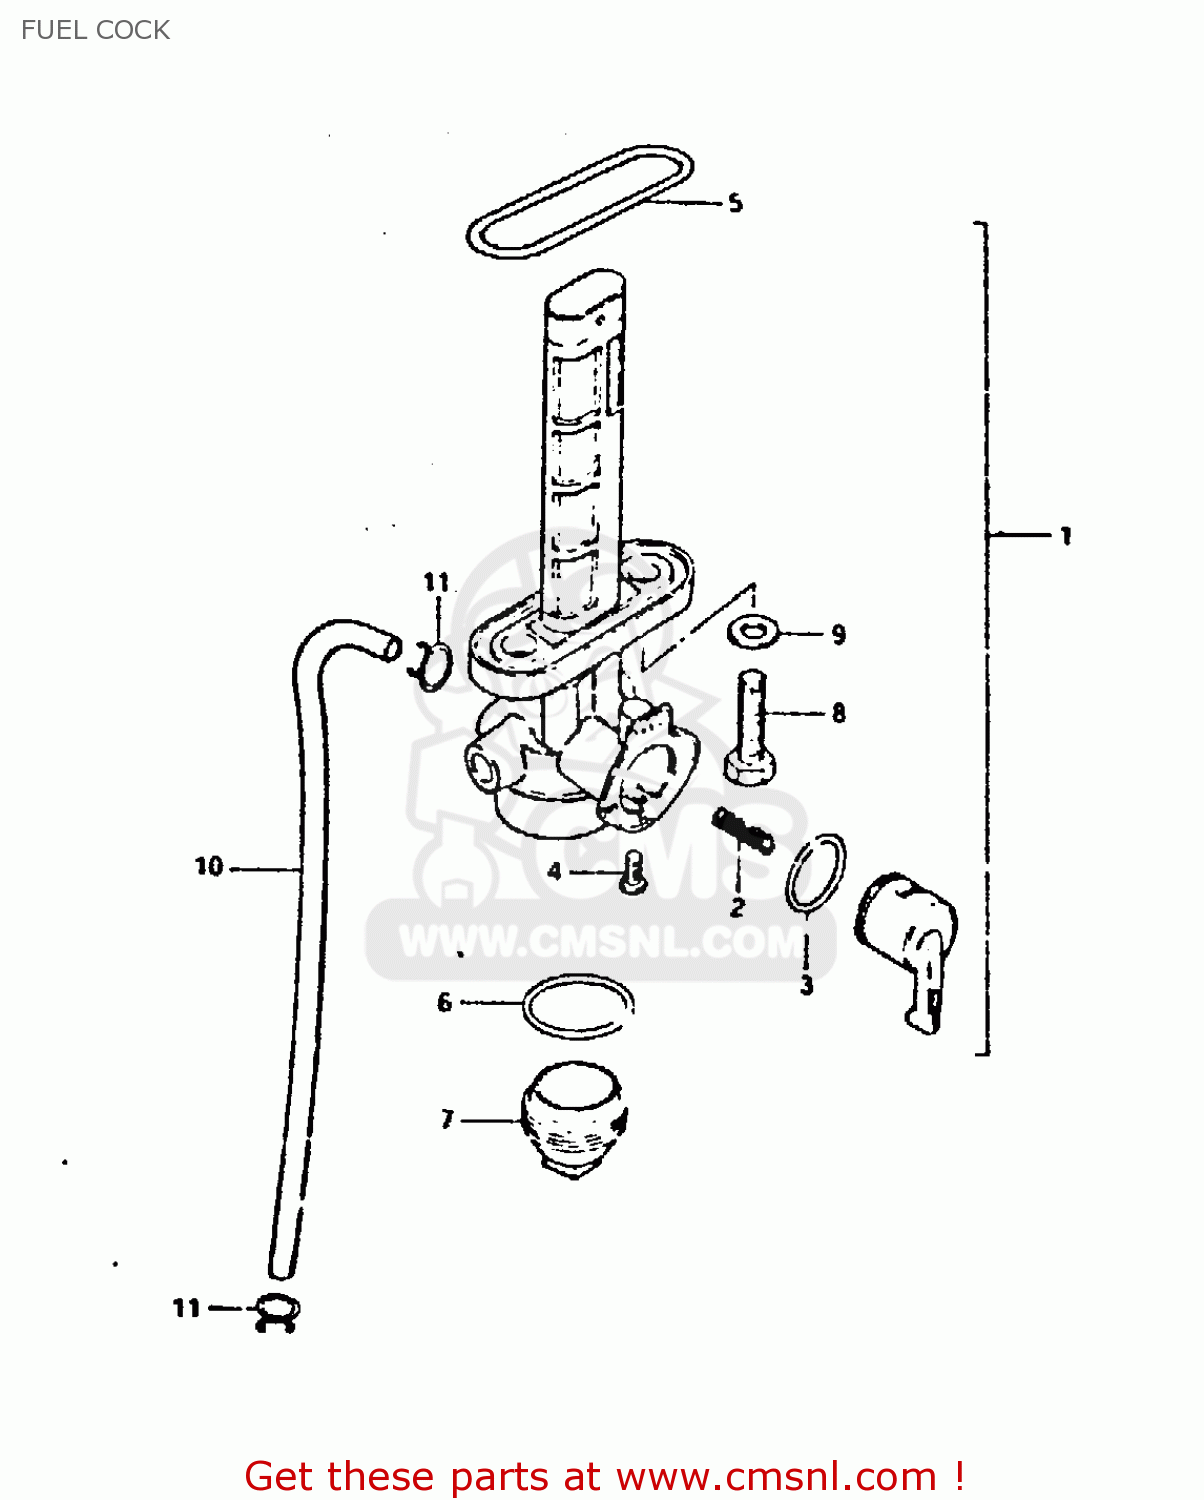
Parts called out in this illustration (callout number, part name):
1	COCK ASSY, FUEL
2	SPRING
3	O-RING
4	SCREW
5	O RING,FUEL COCK
6	GASKET,FILTER (NAS)
7	CUP,STRAINER
8	BOLT(6X20)
9	GASKET
10	HOSE
11	CLIP
